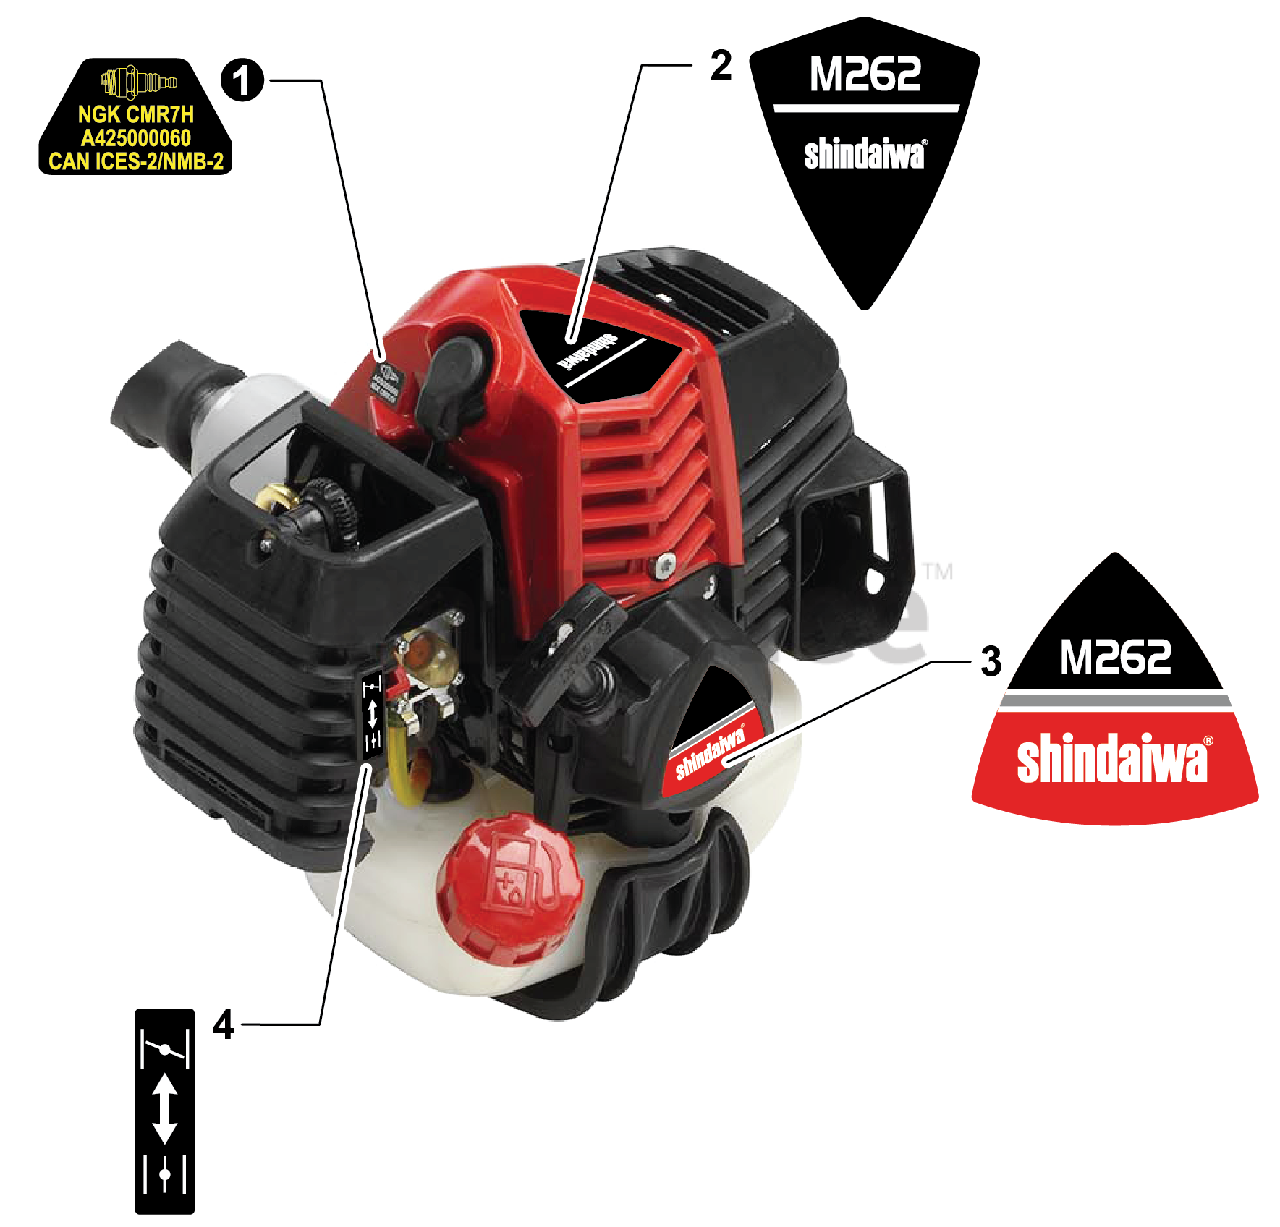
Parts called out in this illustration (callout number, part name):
1	LABEL, SPARK PLUG - CMR7H
2	LABEL - MODEL M262
3	LABEL, RECOIL STARTER - M262
4	LABEL, CHOKE
